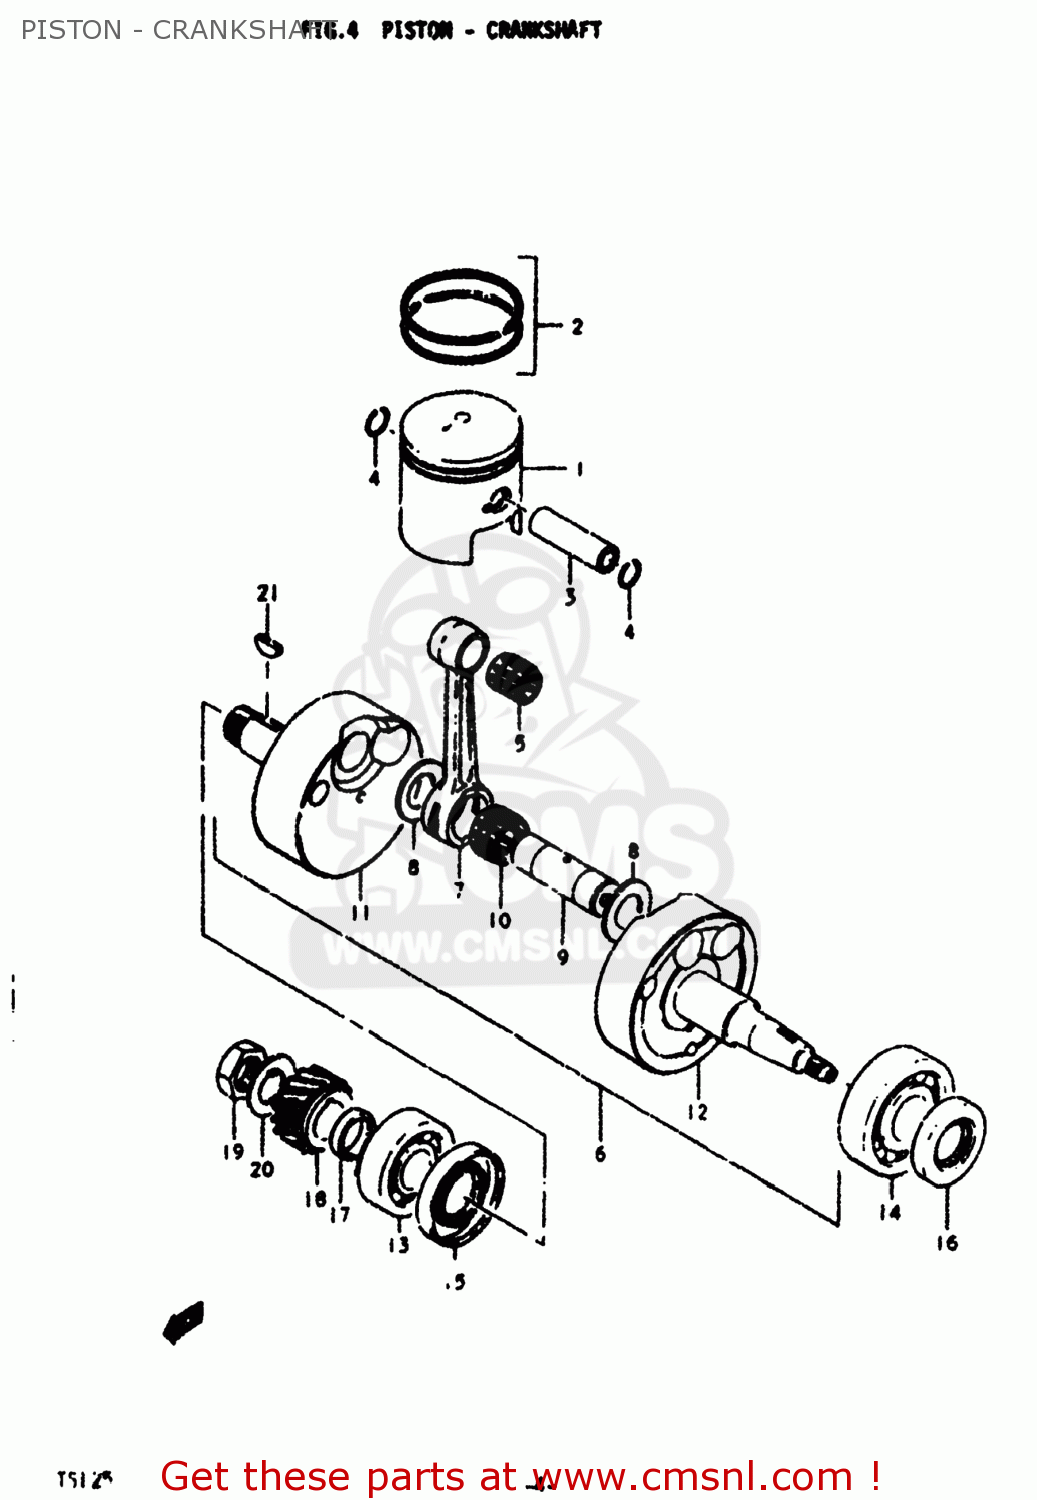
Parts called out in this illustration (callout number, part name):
1	PISTON
2	RING SET,PISTON
3	PIN,PISTON
4	RING,SNAP 14MM
5	BEARING
6	CRANKSHAFT ASSEMBLY
7	CONNECTING ROD
8	WASHER(19X32X1)
9	PIN,CRANK
10	BEARING
11	CRANKSHAFT,R
12	CRANKSHAFT,LEFT
13	BEARING
14	BEARING(25X62X17)
15	SEAL,OIL(26X52X8)
16	OIL SEAL
17	SPACER(20X28X7)
18	GEAR,PRIMARY DRIVE
19	NUT
20	WASHER
21	KEY
